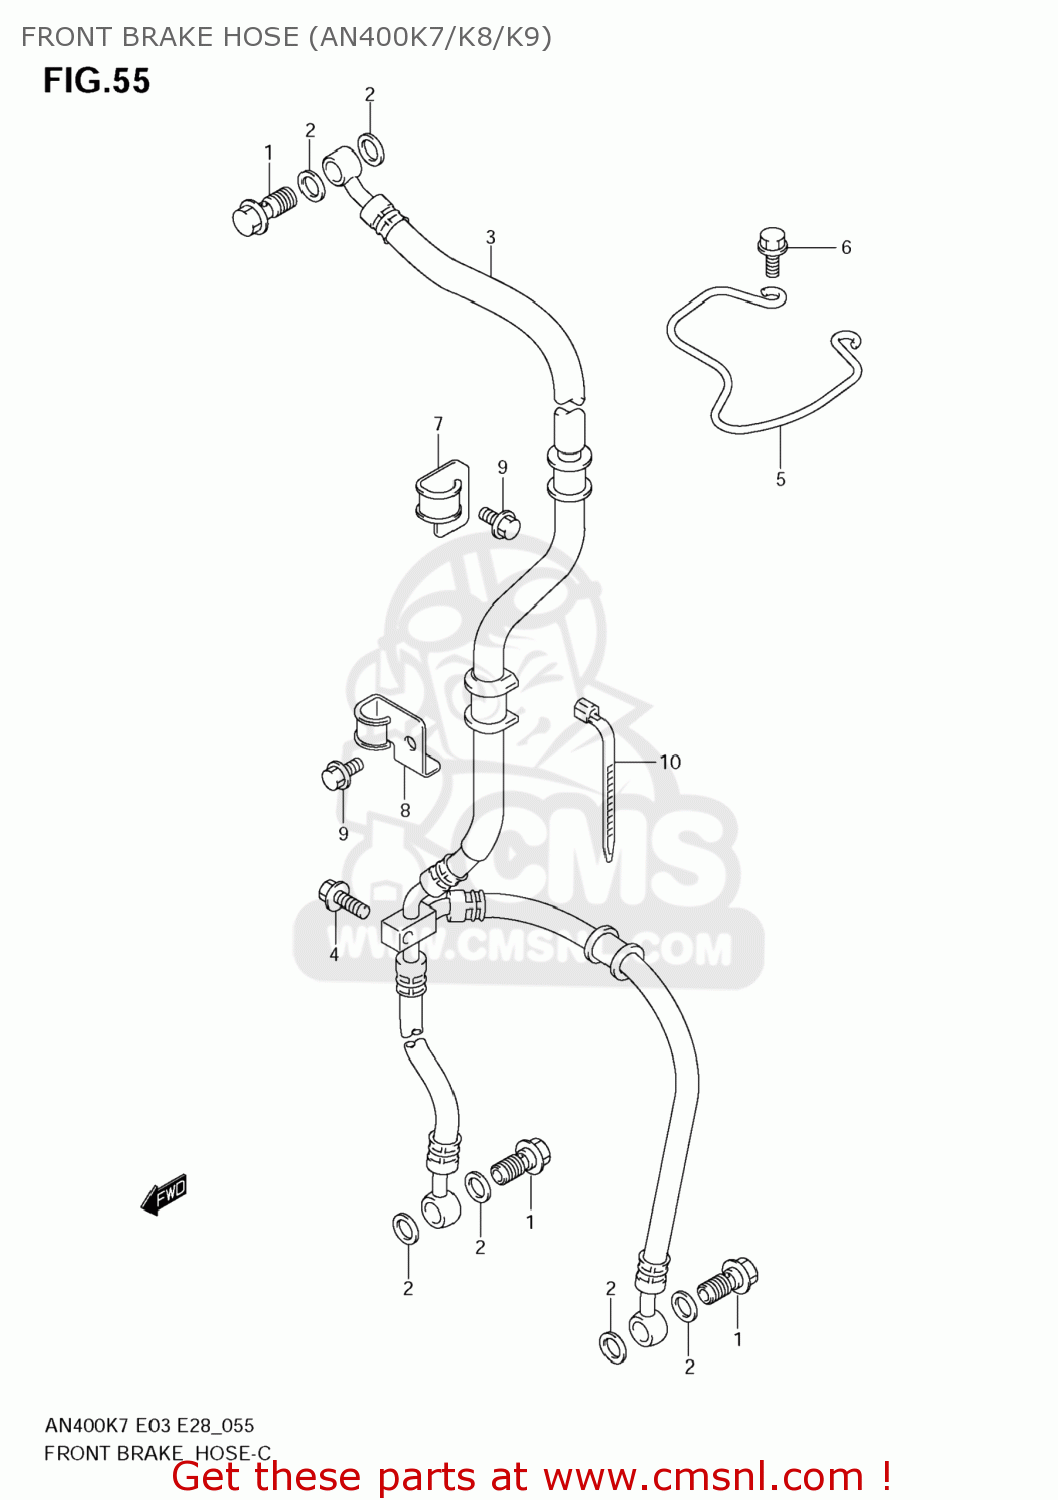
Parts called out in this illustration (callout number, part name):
1	BOLT UNION
2	WASHER(10X15X1.5)
3	HOSE
4	BOLT
5	GUIDE,BRAKE HOSE
6	BOLT
7	CLAMP,FR BRAKE HOSE NO.1
8	CLAMP,FR BRAKE HOSE NO.2
9	BOLT
10	CLAMP
